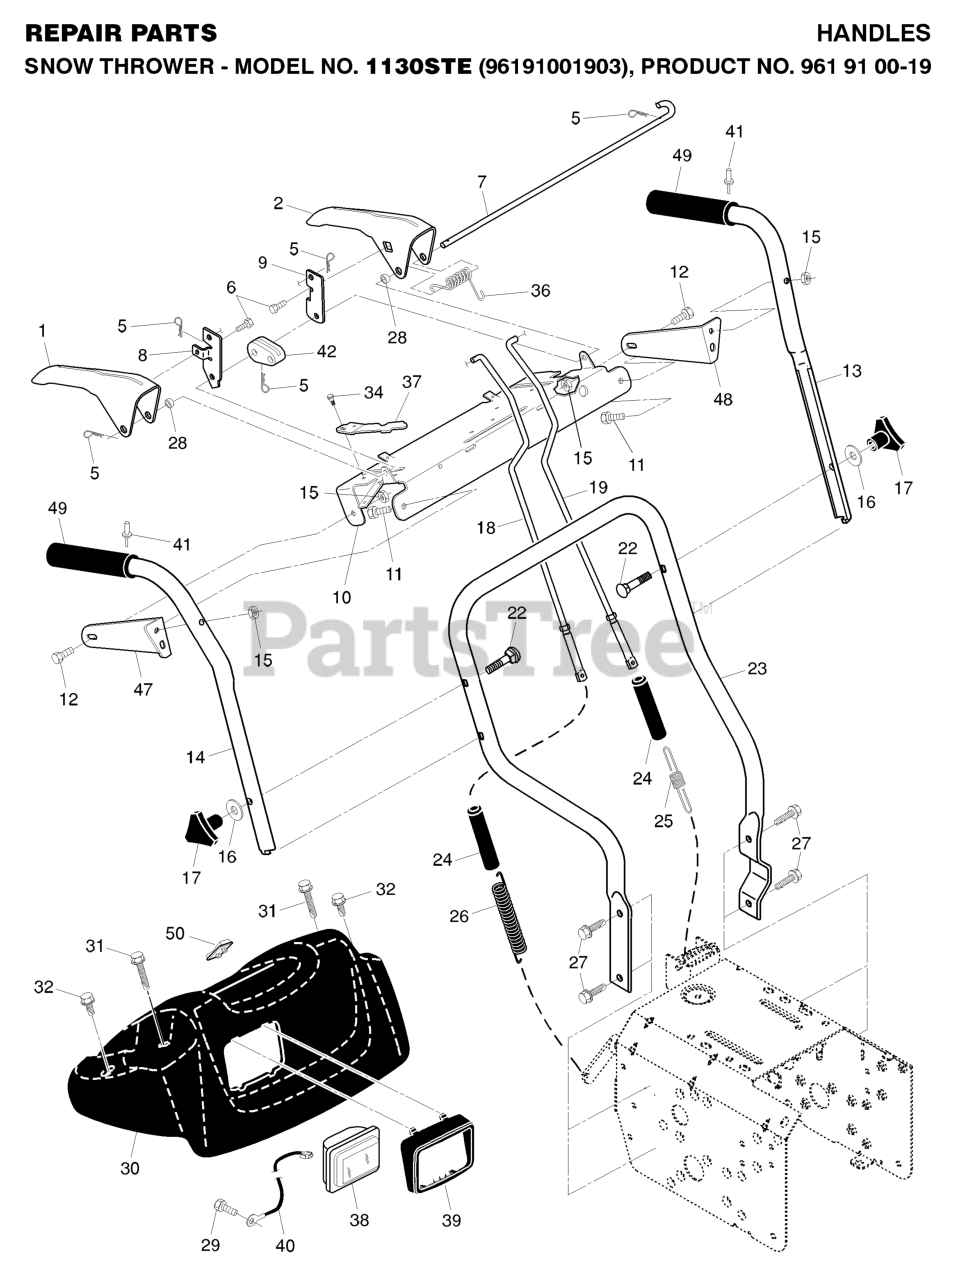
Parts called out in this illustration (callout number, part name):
1	LEVER.CONTROL.RH.PNT
2	LEVER.CONTROL.LH.PNT
5	SPRING RETAINER
7	BAIL.CONTROL.INTERLOCK
8	ARM,IMPELLER ROD
9	ARM.TRACTION.ROD.YZ
10	PANEL.CONTROL.PNT.BLACK
11	HEX BOLT
12	BOLT.FIN.HEX.5/16-18X3/4
13	TUBE.HANDLE.PLOW.LH.PNT
14	TUBE.HANDLE.PLOW.RH.PNT
15	NUT.LOCK.5/16-18
16	WASHER
17	KNOB.HANDLE.3/8.TRI-POINT.BLAC
18	ROD.ASM.IMPELLER
19	ROD.ASM.TRACTION
22	BOLT 3/8-16 X 2-1/4
23	TUBE.LOWER.HANDLE.24.BLACK
24	SLEEVE, SPRING
25	SPRING, TRACTION DRIVE
26	SPRING, AUGER CONTROL
27	SCREW 3/8-16X1
28	SPACER CONTROL LEVER
29	Screw, Grounding
30	CONSOLE, PANEL
31	SCREW, HEX HD TAPPING #10-24 1
32	SCREW, HEX HEAD, TAPPING
34	SCREW 14-20 X 5/8
36	RP SPRING, TORSION
37	SPRING.INTERLOCK
38	HEADLIGHT.HALOGEN.SNOW
39	BEZEL.HEADLIGHT.BLACK
40	HARNESS.WIRE.LIGHT/GRIP.SNOW
41	RIVET.POP.1/8X
42	CAM.INTERLOCK.RELEASE
47	BRKT.PANEL.RH.INT
48	BRKT.PANEL.LH.INT
49	GRIP.HANDLE.HEATED
50	SWITCH.GRIP.HEATED
